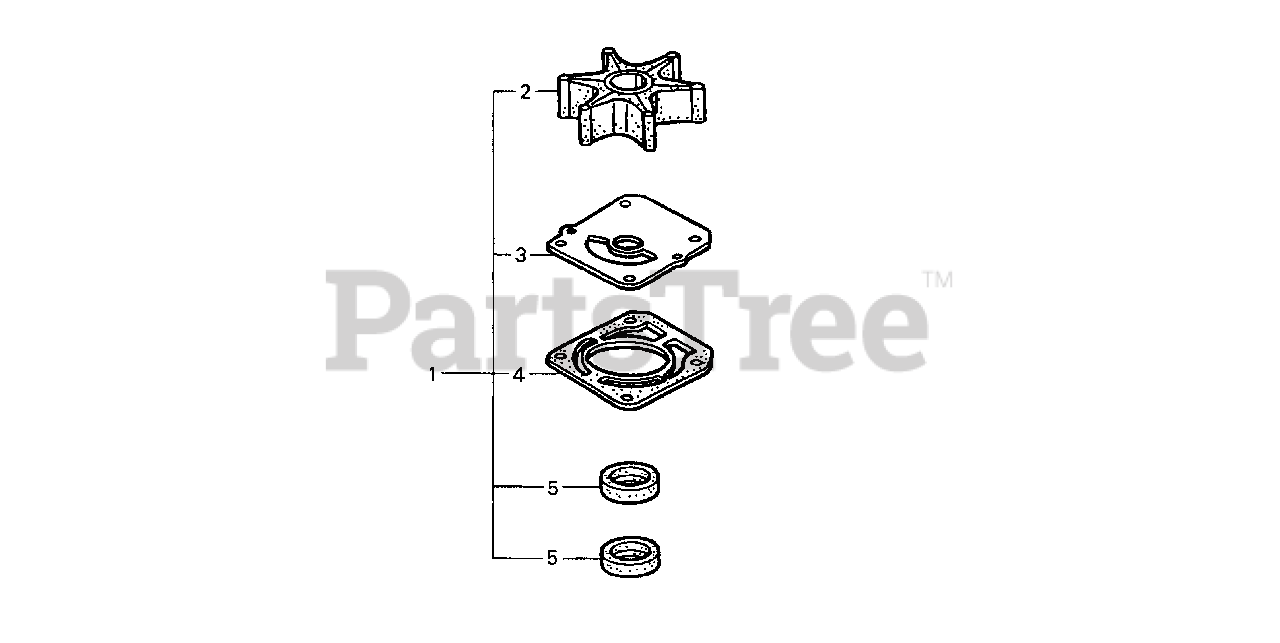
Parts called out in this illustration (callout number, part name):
1	IMPELLER KIT, WATER PUMP Use up to Frame SN 1000210.
1	IMPELLER KIT, WATER PUMP
2	IMPELLER, PUMP
3	GASKET B, IMPELLER
4	GASKET, WATER PUMP
5	SEAL, WATER (23X36X6) Use up to Frame SN 1000210.
5	SEAL, WATER (23X36X6)
